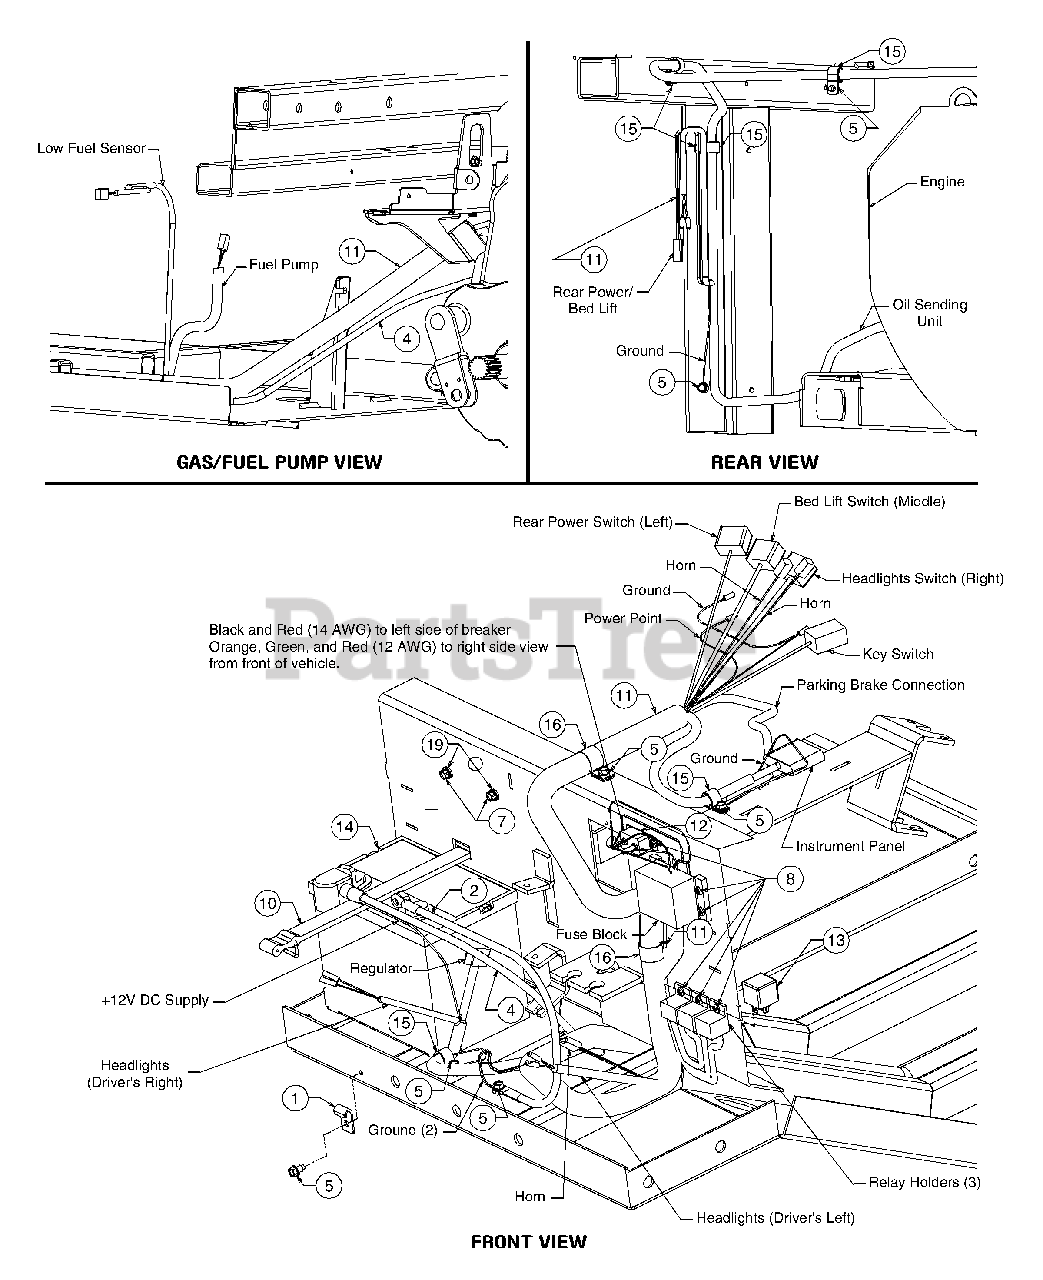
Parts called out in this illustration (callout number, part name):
1	Bracket, Retainer Hook
2	Harness Assembly, Utility Ground
4	Harness Assembly, Positive
5	Screw, Self-tapping, 1/4-20 x 0.500
7	Screw, Self-tapping, 1/4-20 x 1.000
8	Screw, #10-24 x 0.75
10	Strap, Battery
11	Harness, Utility Wire
12	Breaker, 25A
13	Relay, 12V 40A
14	Battery, 300 CCA
15	Clamp, #10
16	Clamp, #14
19	Lock Washer, 1/4
